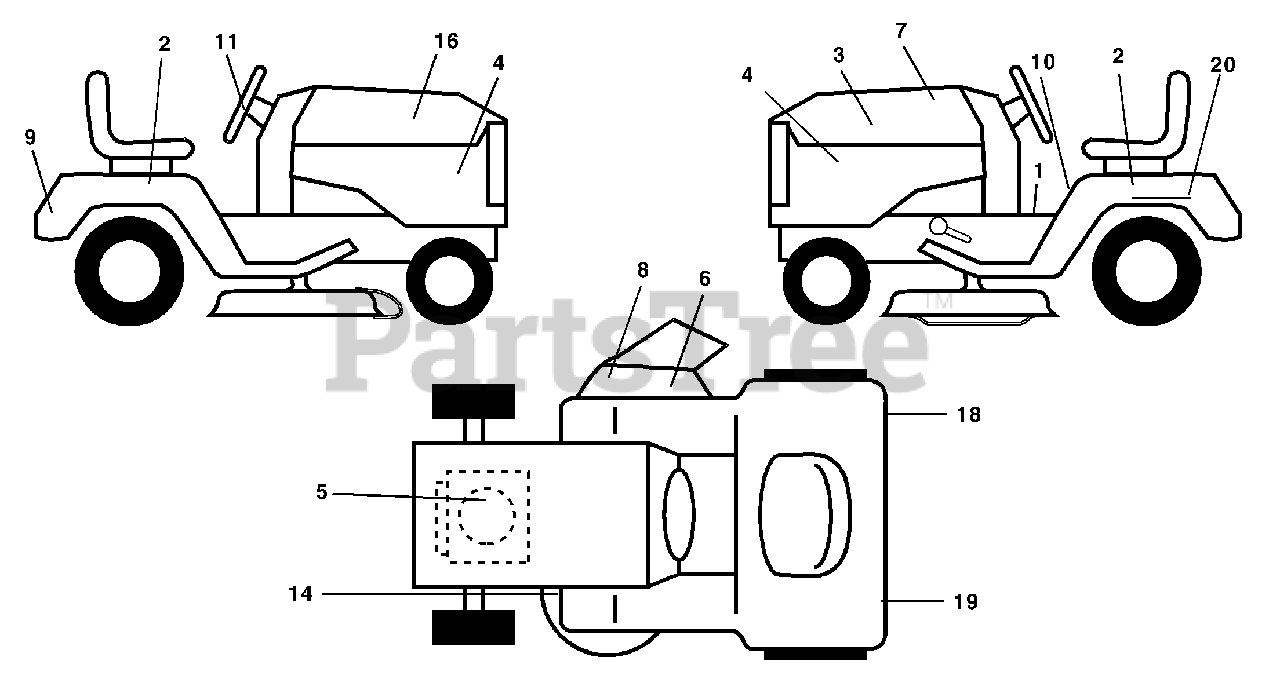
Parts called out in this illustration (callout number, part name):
2	Decal Fender Side
3	Decal Hood LH
4	Decal Side Panel Logo
5	Decal HP Engine
6	Decal Deck "B" 42"
7	Decal Repl. Parts
8	Decal Warning Mult-Language
9	Decal Fender Logo
10	Decal Fender Danger E/F
11	Decal Ins Strg Whl
14	Decal V-Belt Schematic
16	Decal Hood Rh
18	Decal Fender Reflector RH
19	Decal Fender Reflector LH
20	Decal Bat Dan/Psn
